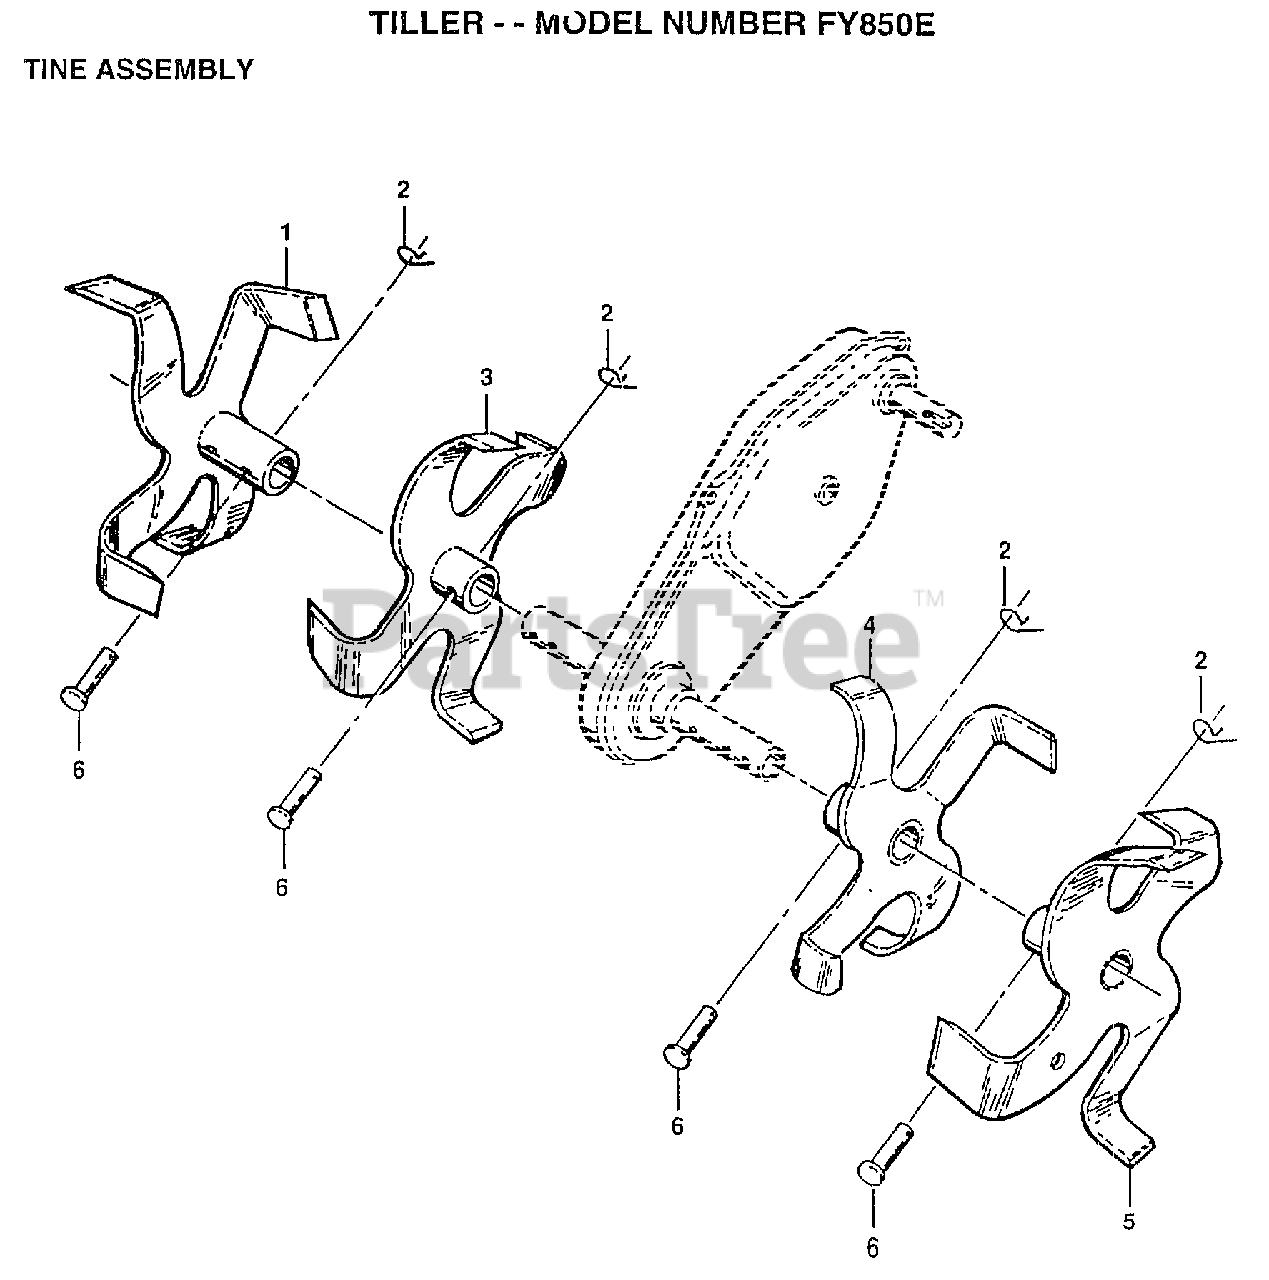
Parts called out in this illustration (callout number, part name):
1	TINE OUTER RH T
2	RETAINER.SPRING
4	TINE.INNER.LH
5	TINE.OUTER.LH.T
6	RIVET.PAN HD.1.75
